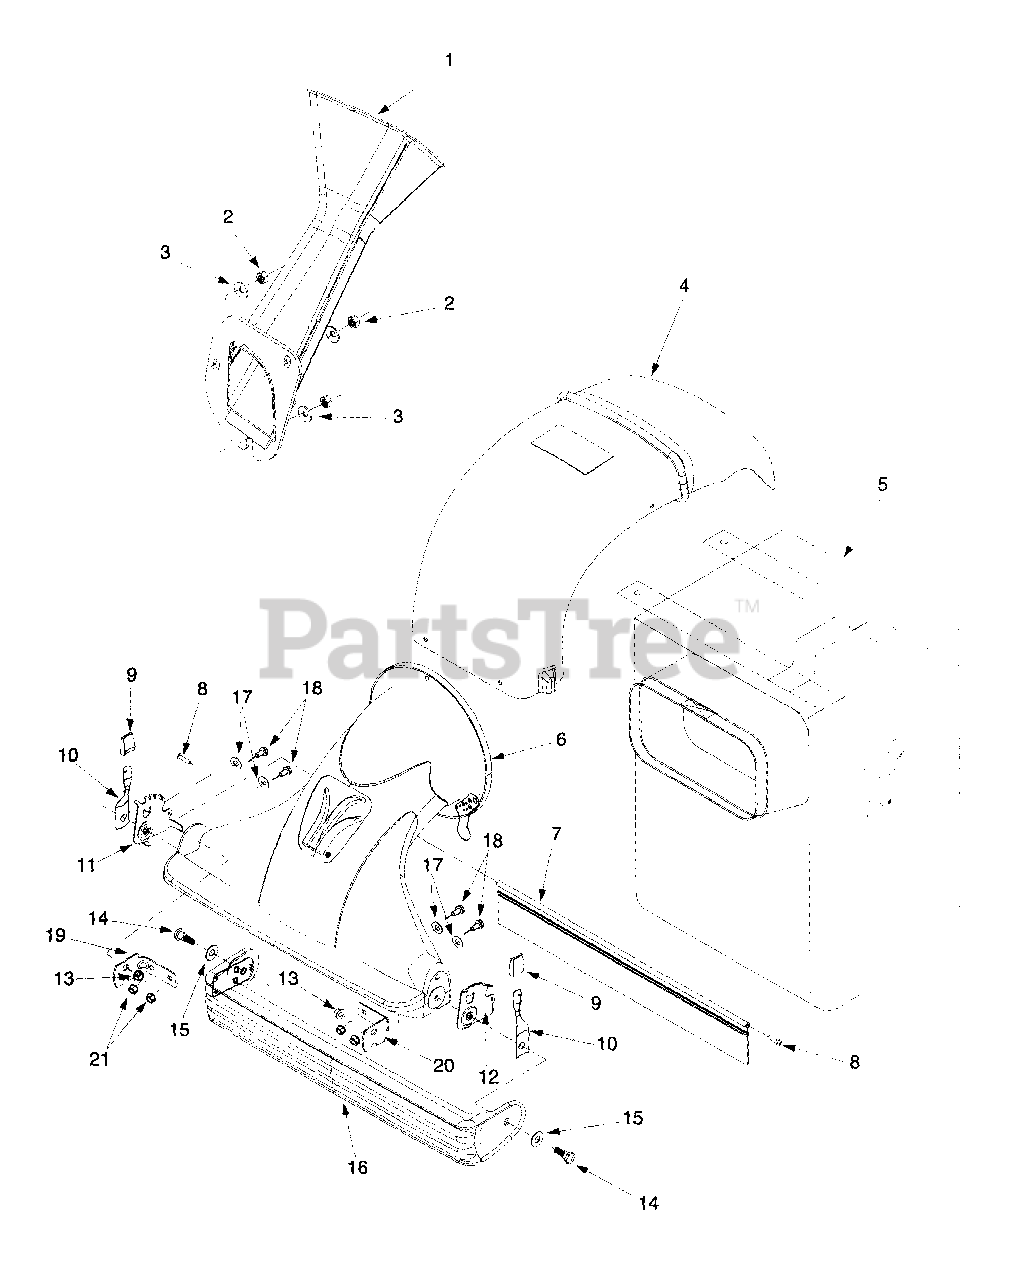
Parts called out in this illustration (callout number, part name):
2	Hex Nut 5/16-18
3	Bell Washer .340 ID x .872 OD
4	Discharge Chute
5	Bag
6	Nozzle Asm
7	Nozzle Flap
8	Screw
9	Height Adjustment Knob
10	Spring Lever
13	Hex Flange Lock Nut 3/8-16
14	Shoulder Screw
15	Flat Washer .510 x 1.12 x .060
16	Door Asm
17	Flat Washer .28 ID x .74 OD
18	Hex Cap Screw 1/4-20 x .625
